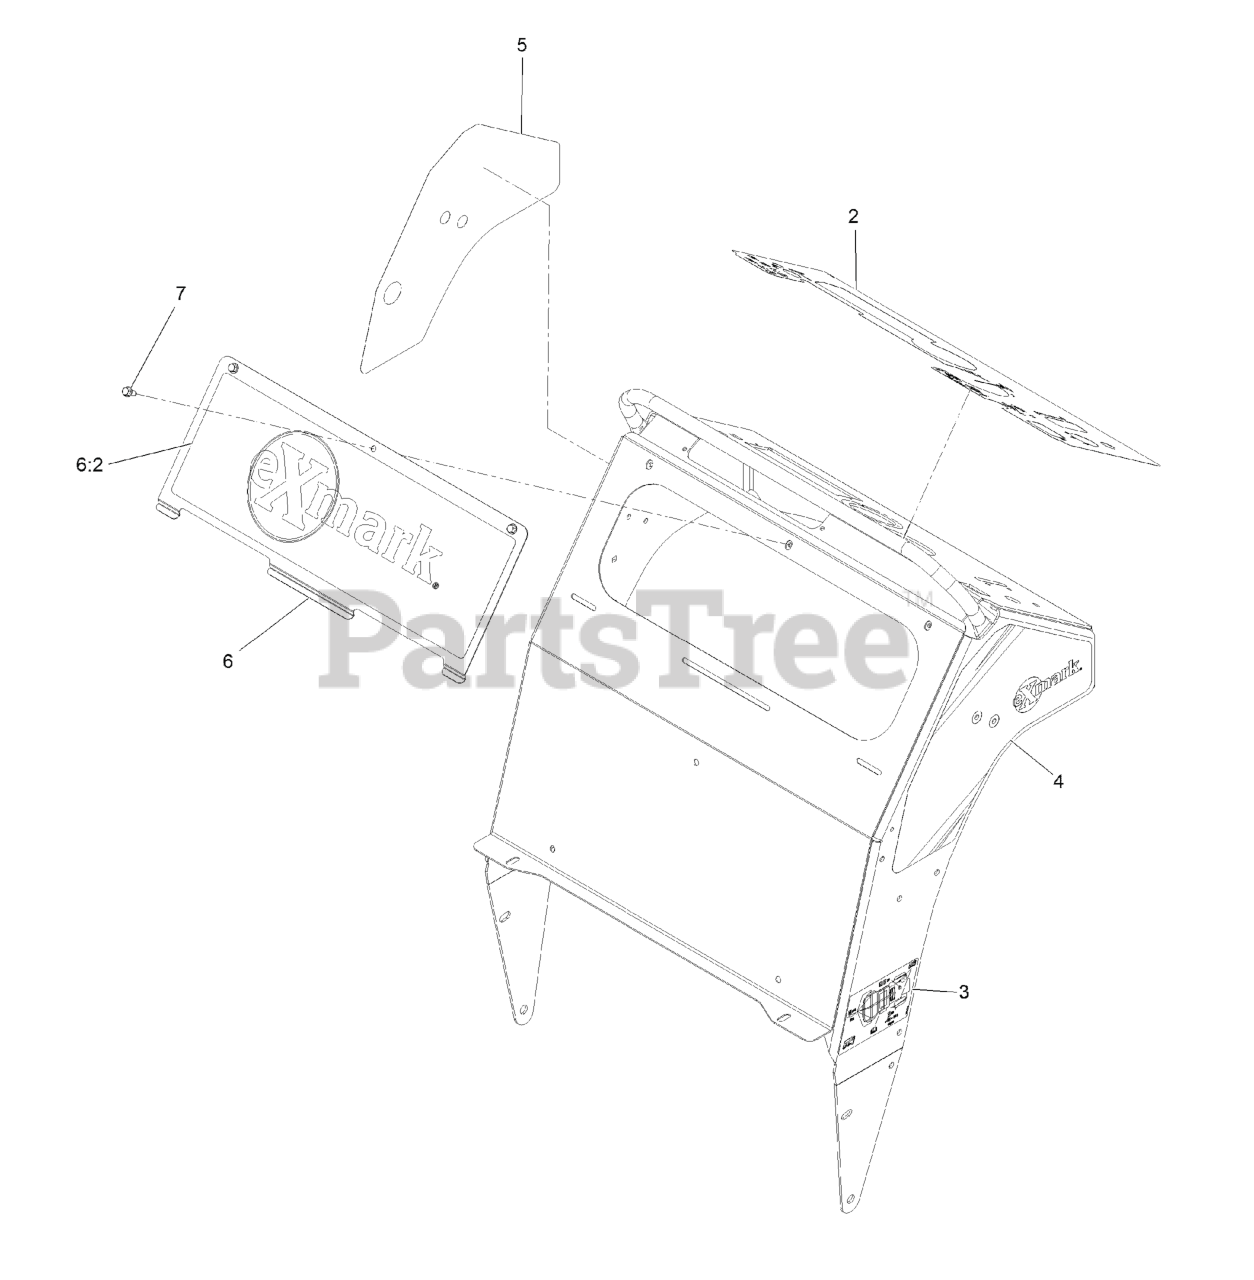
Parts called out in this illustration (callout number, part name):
2	DECAL-CONTROL
3	DECAL-SERVICE AID
4	DECAL-LH SIDE PANEL
5	DECAL-RH SIDE PANEL
6	ACCESS PANEL W/ DECAL
6:2	Decal-Exmark Front Panel
7	SCREW-HWH
